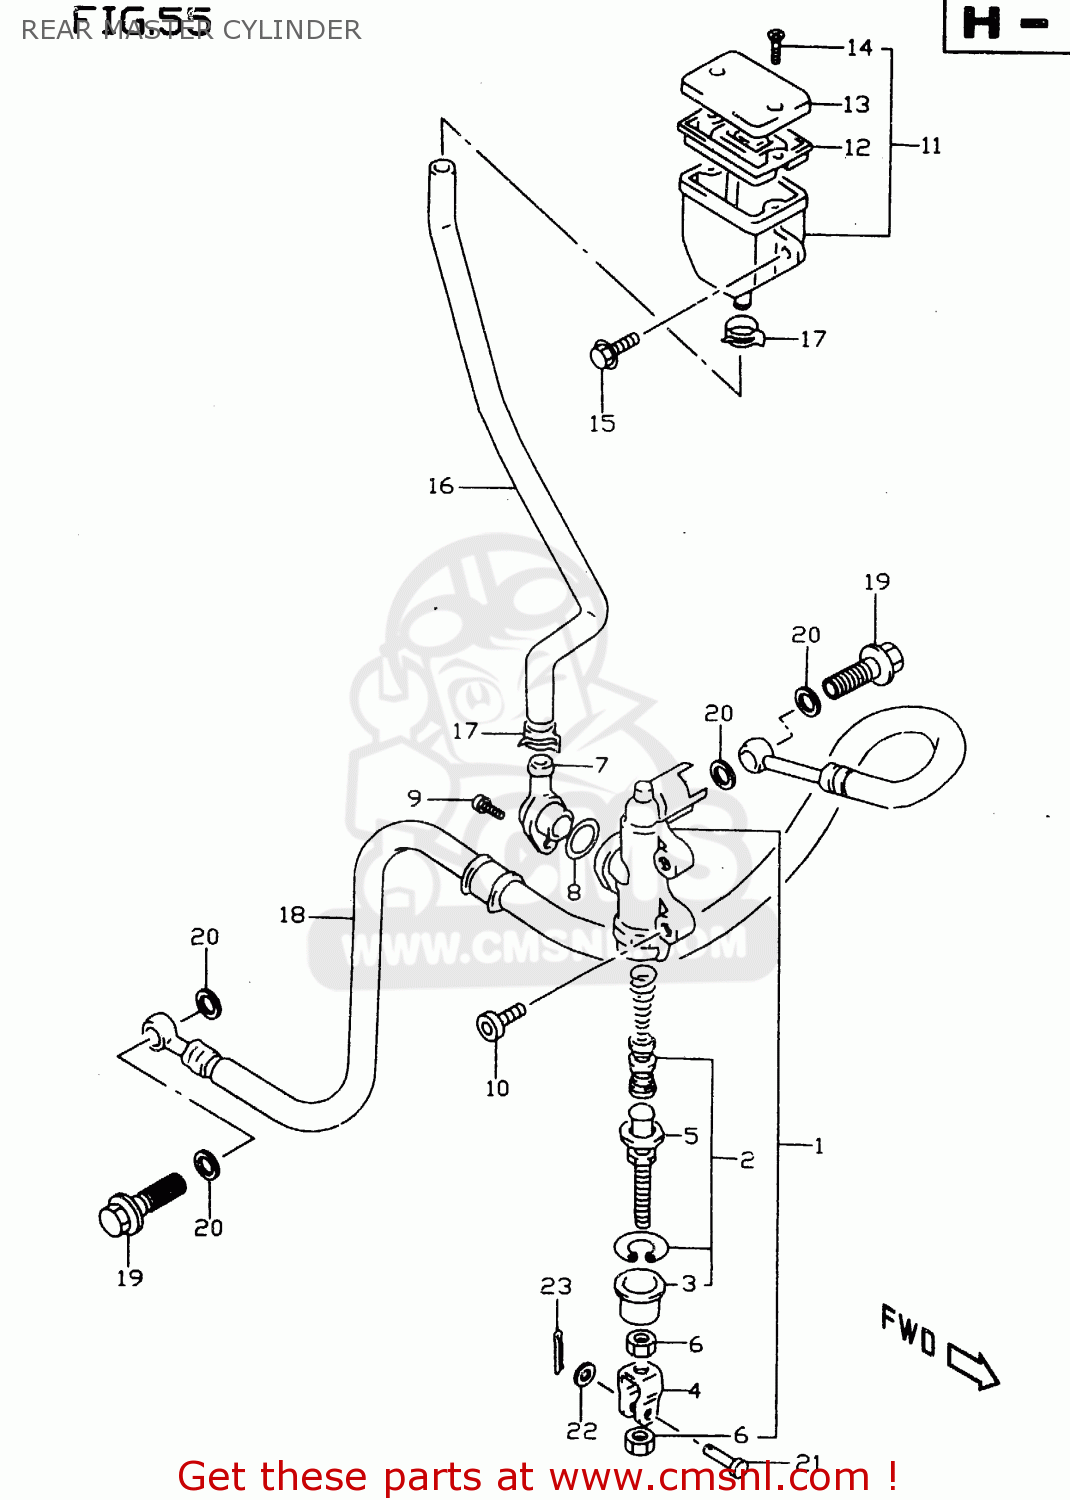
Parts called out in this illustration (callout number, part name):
1	CYLINDER ASSY,RR MASTER
2	PISTON/CUP SET
3	BOOT
4	YOKE
5	ROD,PUSH
6	NUT
7	CONNECTOR
8	O RING
9	SCREW
10	SCREW(6X16)
11	TANK ASSY,RESERVOIR
12	DIAPHRAGM
13	CAP
14	SCREW
15	BOLT
16	HOSE,RESERVOIR TANK
17	CLIP
18	HOSE, REAR BRAKE
19	BOLT UNION
20	WASHER(10X15X1.5)
21	PIN
22	WASHER
23	PIN
